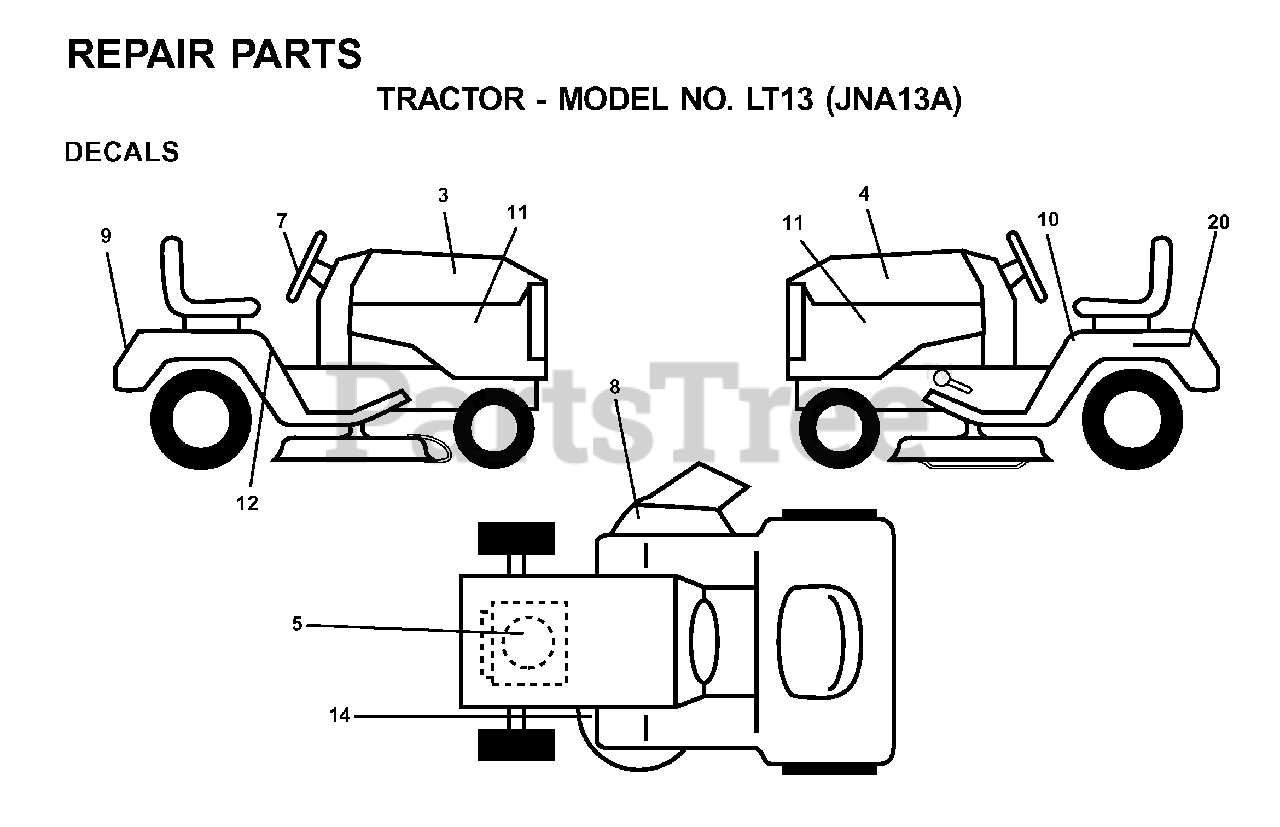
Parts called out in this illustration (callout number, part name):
5	DECAL HP ENGINE
8	DECAL.WARN.KEEP.HAND.AWAY
10	DECAL FEND STLT OPER INST E/F
12	DECAL FENDER DANGER
14	DECAL V-BELT SCHEMATIC
20	DECAL BTRY SYMBOLS
